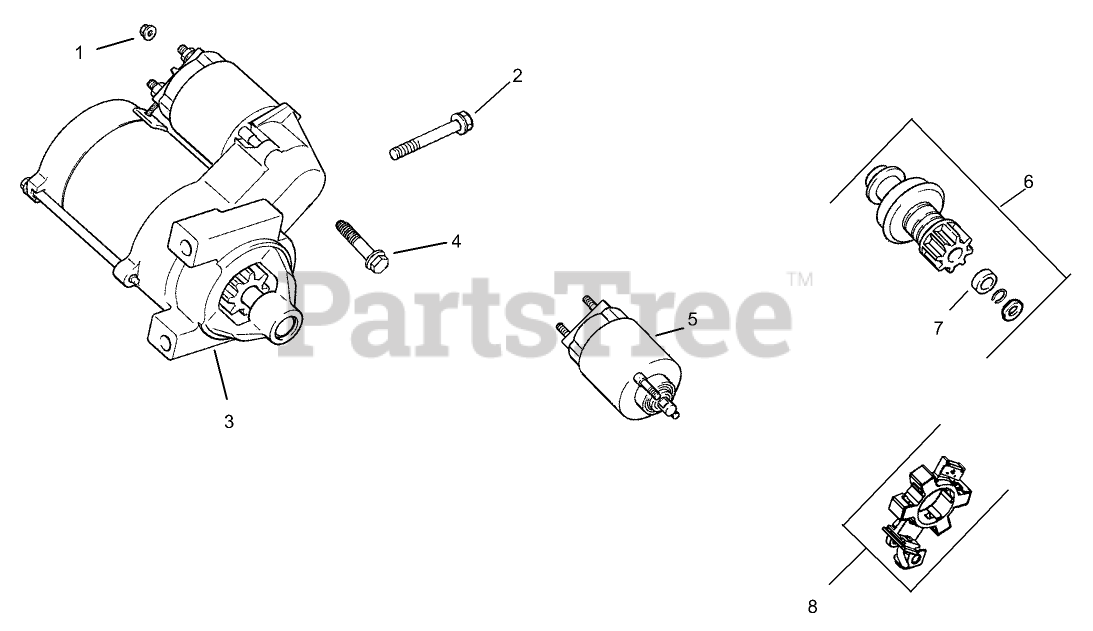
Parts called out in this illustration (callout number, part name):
1	NUT-FLANGE (M8X1.25)
2	SCREW-FLG (M8X1.25X80)
3	Starter, solenoid shift assembly (Includes 4-8)
4	SCREW-TORX HEAD, EXTERNAL
5	Kit, solenoid (Includes 4)
6	Kit, pinion drive (Includes 7)
7	RING-RETAINING
8	BRUSH HOLDER KIT
